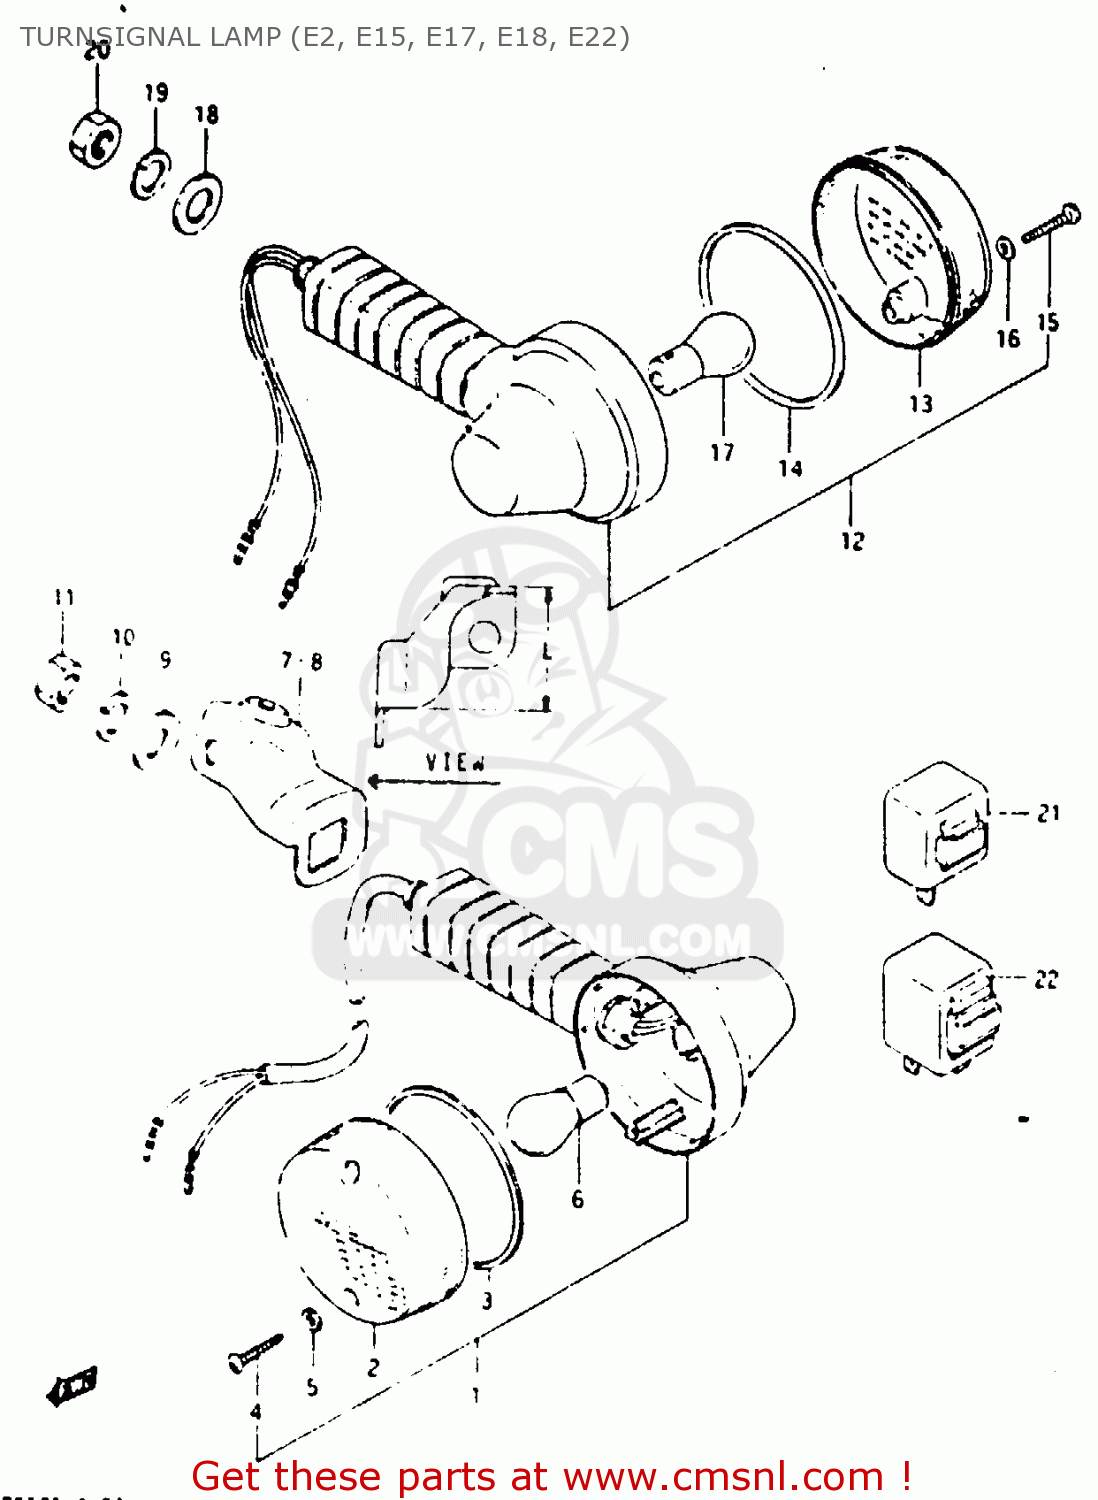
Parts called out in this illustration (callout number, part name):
1	LAMP ASSY, FRONT TURNSIGNAL
2	LENS
3	GASKET (NAS)
4	SCREW TAPP.
5	GASKET (NAS)
6	BULB(12V21W)
7	BRACKET, FRONT RH
8	BRACKET, FRONT LH
9	WASHER (12.5X26X1.6)
10	WASHER
11	NUT 12MM
12	LAMP ASSY, REAR TURNSIGNAL
13	LENS
14	GASKET (NAS)
15	SCREW TAPP.
16	GASKET (NAS)
17	BULB(12V21W)
18	WASHER (12.5X26X1.6)
19	WASHER
20	NUT 12MM
21	RELAY ASSEMBLY,TURN SIGNAL
